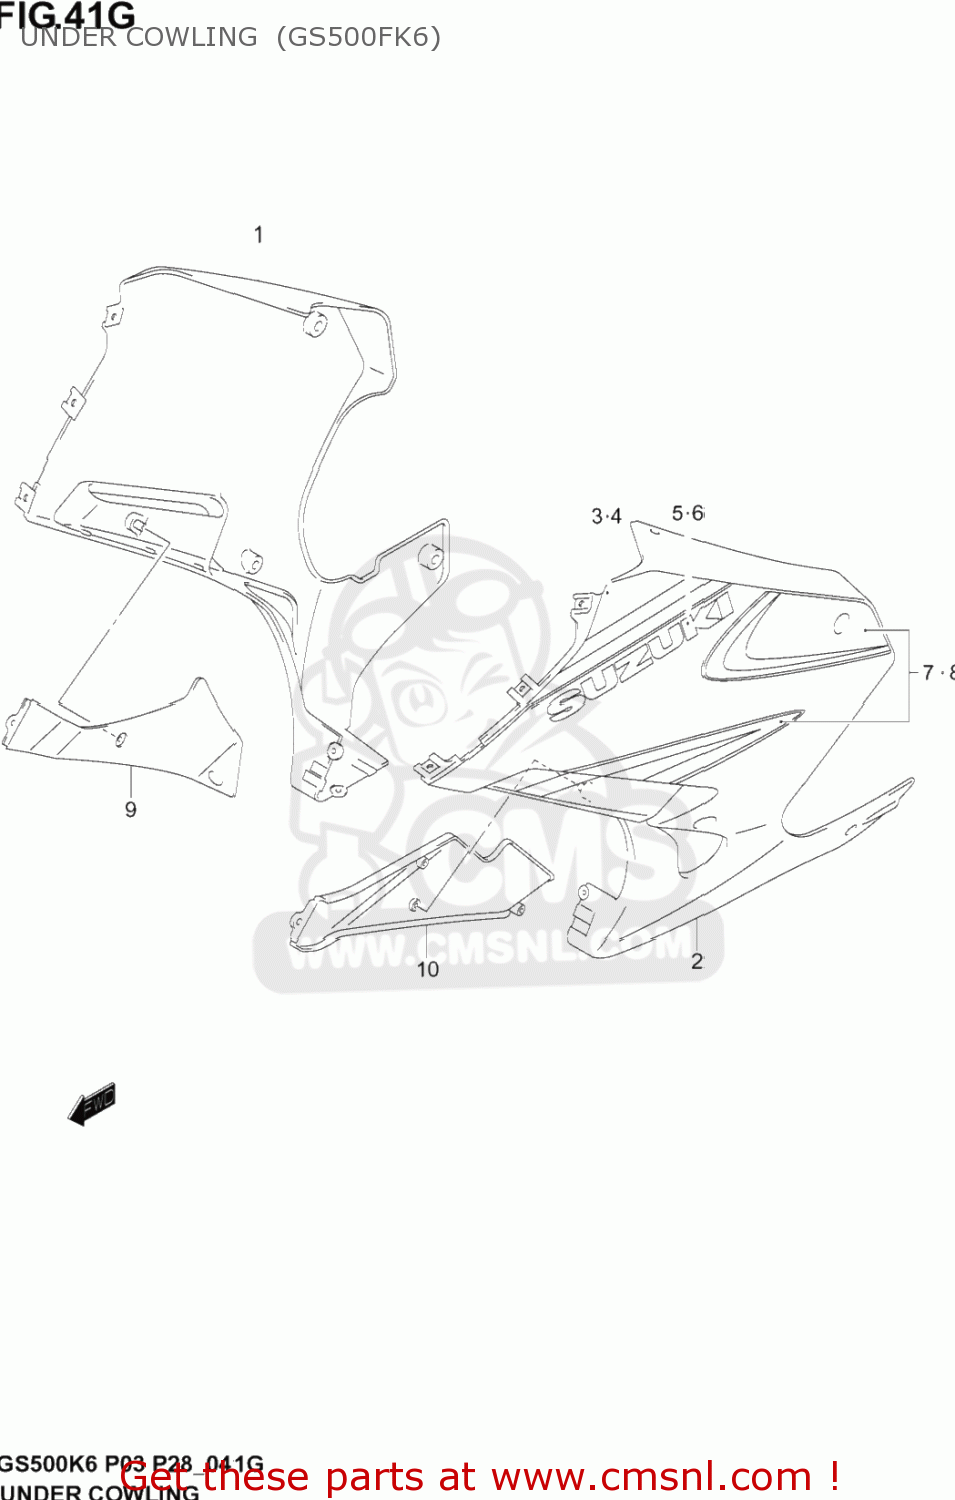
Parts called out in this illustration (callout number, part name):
1	COWL, UNDER RH (WHITE)
2	COWL, UNDER LH (WHITE)
3	TAPE GS500
4	TAPE,UPPER
5	EMBLEM SET RH
6	EMBLEM SET RH
7	EMBLEM SET RH
8	EMBLEM SET RH
9	COWL, INNER RH
10	COWL, INNER LH
11	SHIELD,UNDER C
12	SHIELD,UNDER C
13	SHIELD,UN. HEA
14	SHIELD,UN.HEAT
